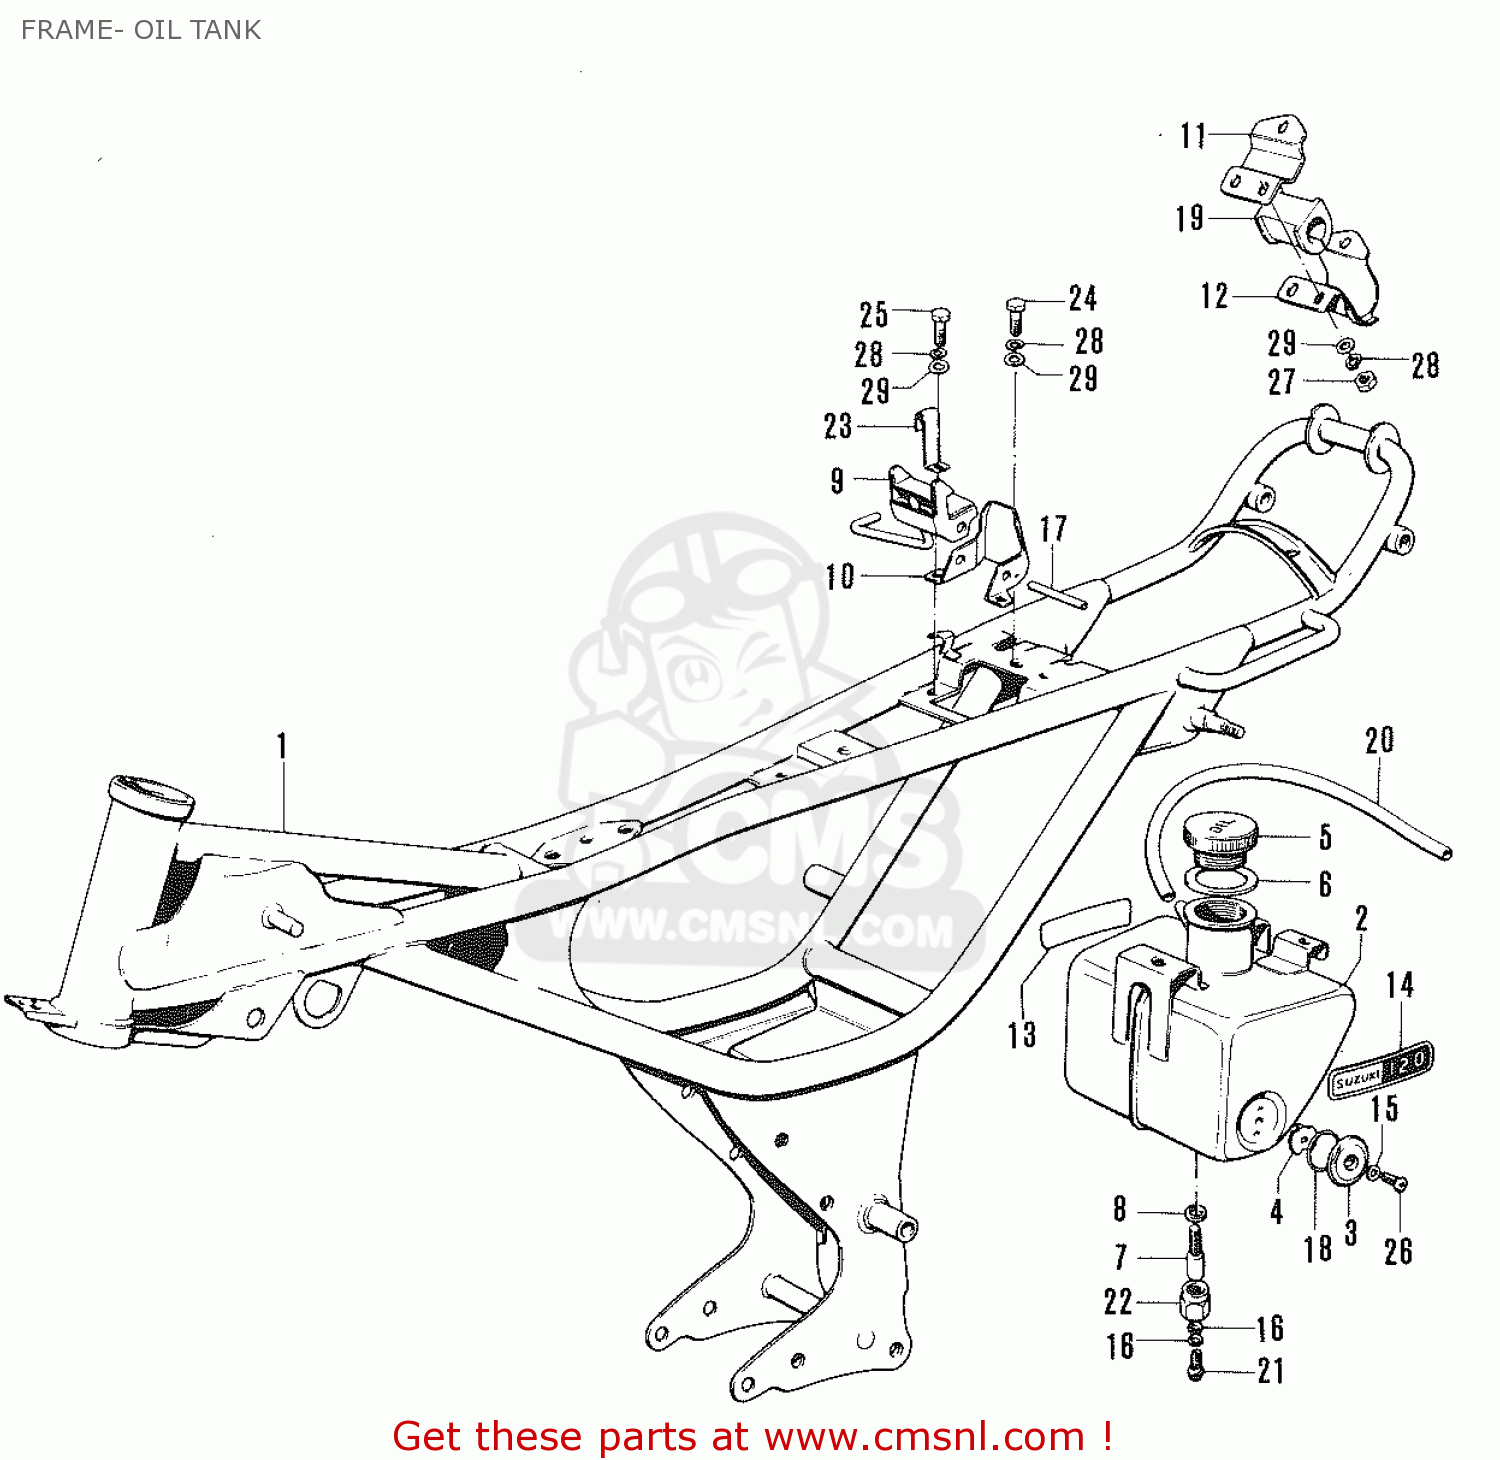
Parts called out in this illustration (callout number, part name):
1	FRAME
2	TANK,OIL
3	LENS,INSPECTION
4	PLATE,OIL LEVEL INSPECTION
5	CAP,OIL TANK
6	GASKET,OIL TANK FILLER CAP (NAS)
7	UNIT,OIL FILTER
8	GASKET,OIL OUTLET JOINT (NAS)
9	DUAL SEAT CLAMP
10	SEAT CLAMP GUIDE PLATE
11	SEAT FITTING UPPER BRACKET
12	SEAT FITTING LOWER BRACKET
13	EMBLEM
14	GASKET(5X9.5X1) (NAS)
15	GASKET (NAS)
16	PIN
17	O RING(D:3,ID:23)
18	BUSHING
19	HOSE
20	UNION BOLT
21	OIL OUTLET JOINT NUT
22	CLAMP
23	BOLT
24	BOLT
25	SCREW
26	NUT
27	LOCK WASHER
28	WASHER
